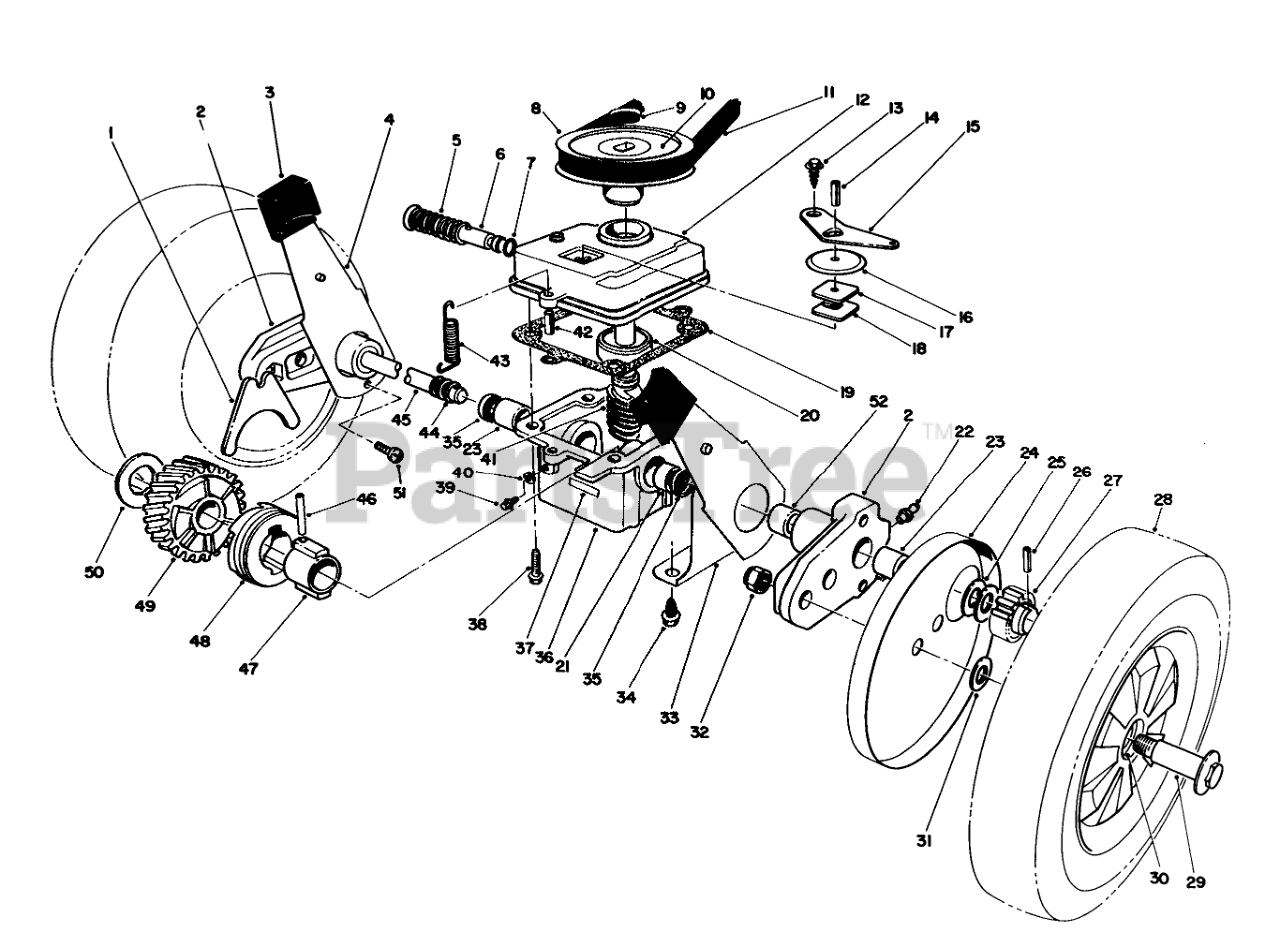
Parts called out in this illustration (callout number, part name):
1	SHIFTER FORK
2	Arm-Pivot (Incl. Ref. #22, 23 & 52)
3	KNOB-ARM
4	SPRING ARM ASSY-FRONT
5	SPRING
6	SHIFTER ROD
7	O-RING
8	PULLEY
9	PUSH-ON 93-3236
10	DECAL
11	V BELT
12	GEAR CASE COVER
13	Screw
14	SPIROL PIN H D
15	SHIFTER ARM
16	DUST COVER
17	DUST FILTER
18	LATCH PLATE
19	GASKET
20	BEARING
21	BUSHING
22	FITTING-GREASE
23	BUSHING
24	Cover-Wheel
25	THRUST WASHER
26	Pin
27	PINION GEAR 15T
28	Wheel, Tire, & Gear Ass-y (Incl. Ref. #30)
29	BOLT-WHEEL
30	BUSHING
31	WASHER
32	Nut
33	END CAP
34	SCREW-HWHTF
35	SEAL-OIL
36	Gear Case (Incl. Ref. #21, 23, & 35)
37	DECAL
38	Screw
39	NYLON SCREW
40	FILL PLUG GASKET
41	Worm Shaft & Gear (Incl. Ref. #49)
42	3/16 X 1/2 ROLL PIN
43	TENSION SPRING
44	COVER-SHAFT, DRIVE
45	DRIVE SHAFT
46	COIL PIN
47	SLEEVE
48	CLUTCH JAW
49	Helical Gear
50	THRUST WASHER
51	SCREW
52	BUSHING
